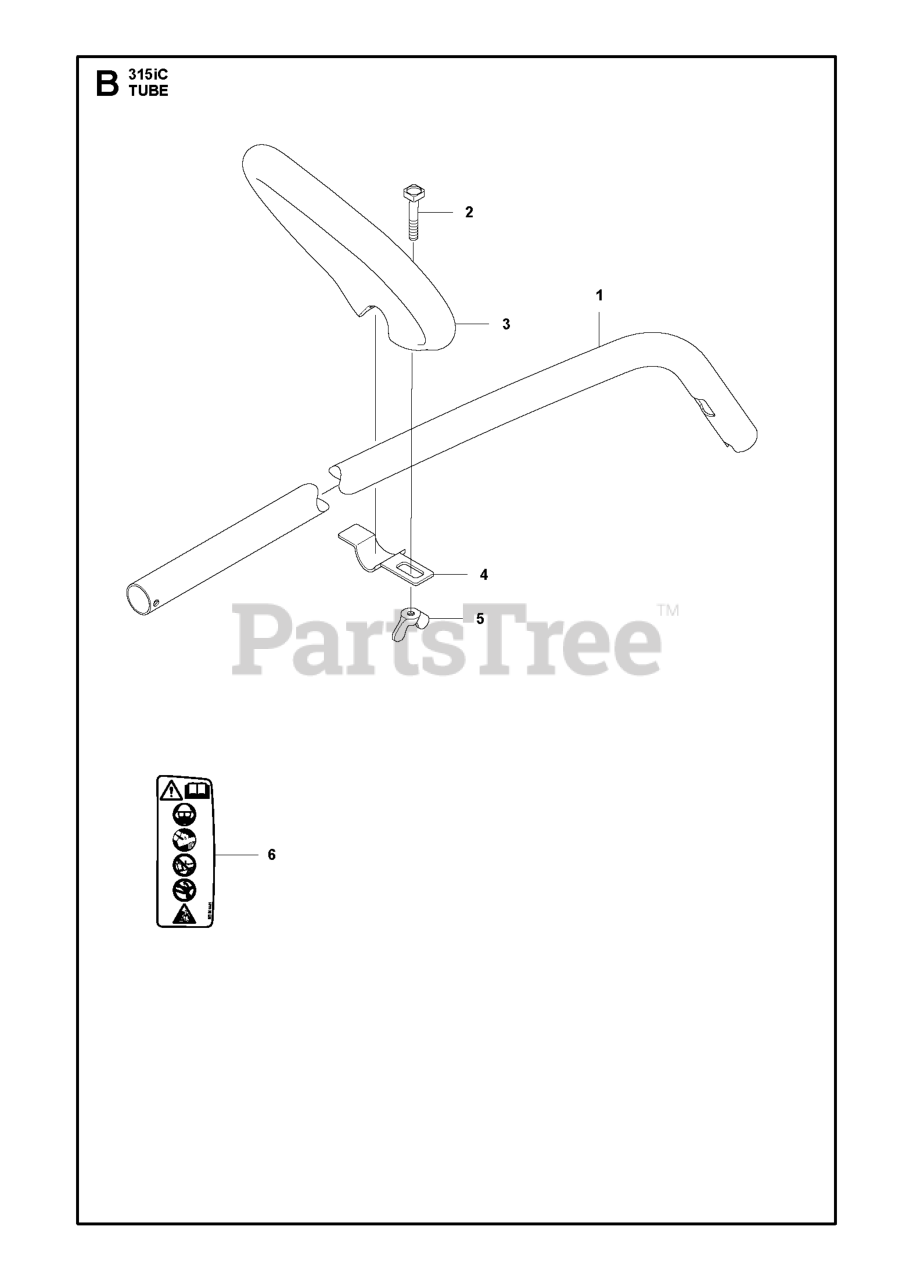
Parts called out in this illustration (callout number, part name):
1	TUBE 336LIC
3	HANDLE, LOOP
4	HOLDER
6	LABEL WARNING TRIMMERS AND BRU
